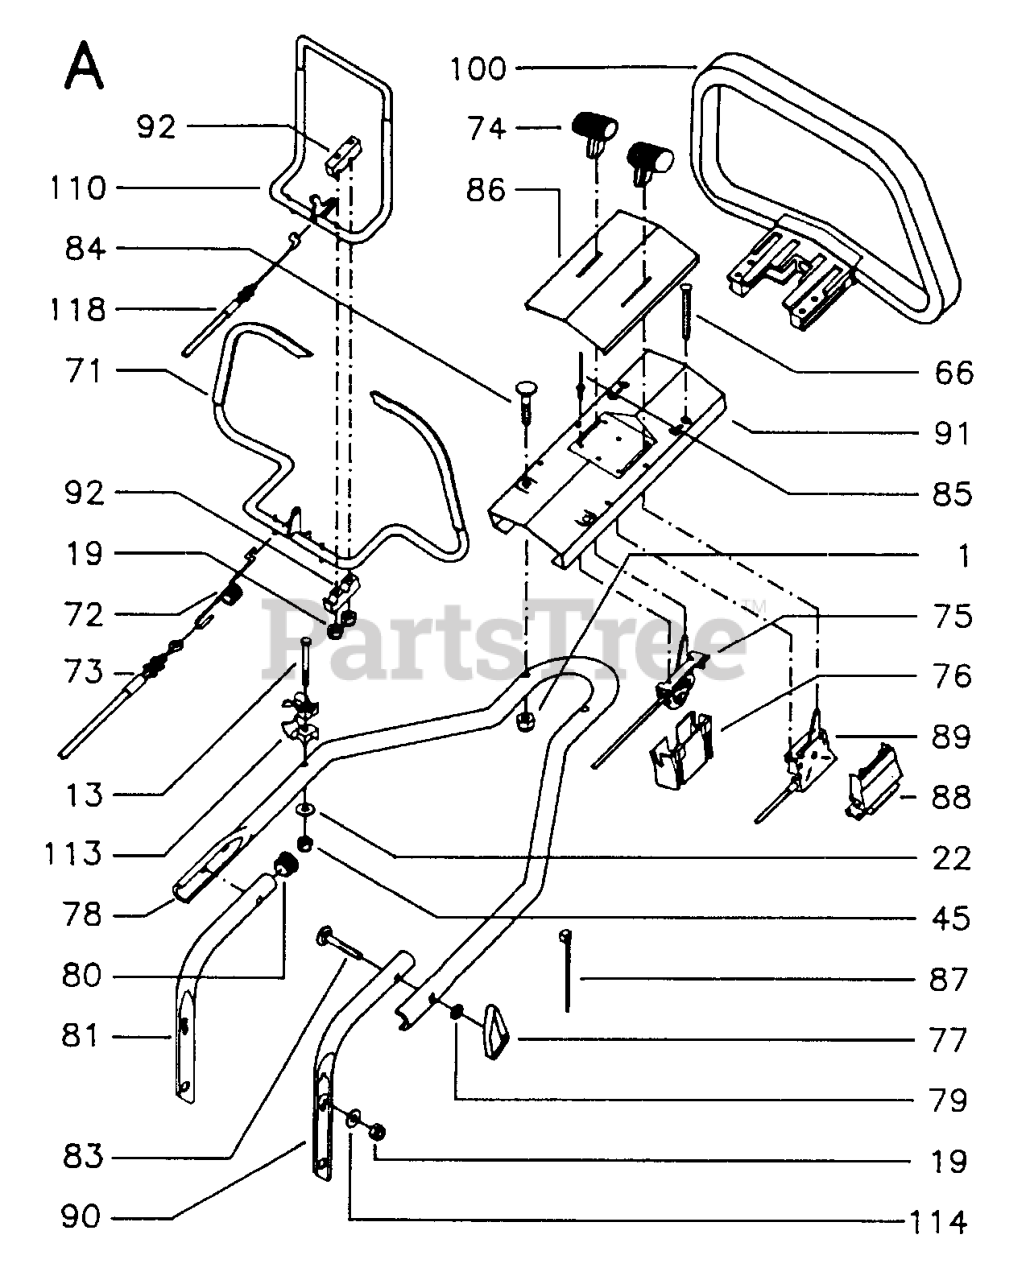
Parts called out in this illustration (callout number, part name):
1	LOCKNUT M8
19	LOCKNUT M6
77	WINGNUT
79	WASHER - 15X7.3X1.6
81	HANDLE
89	THROTTLE TRIGGER
90	HANDLE
